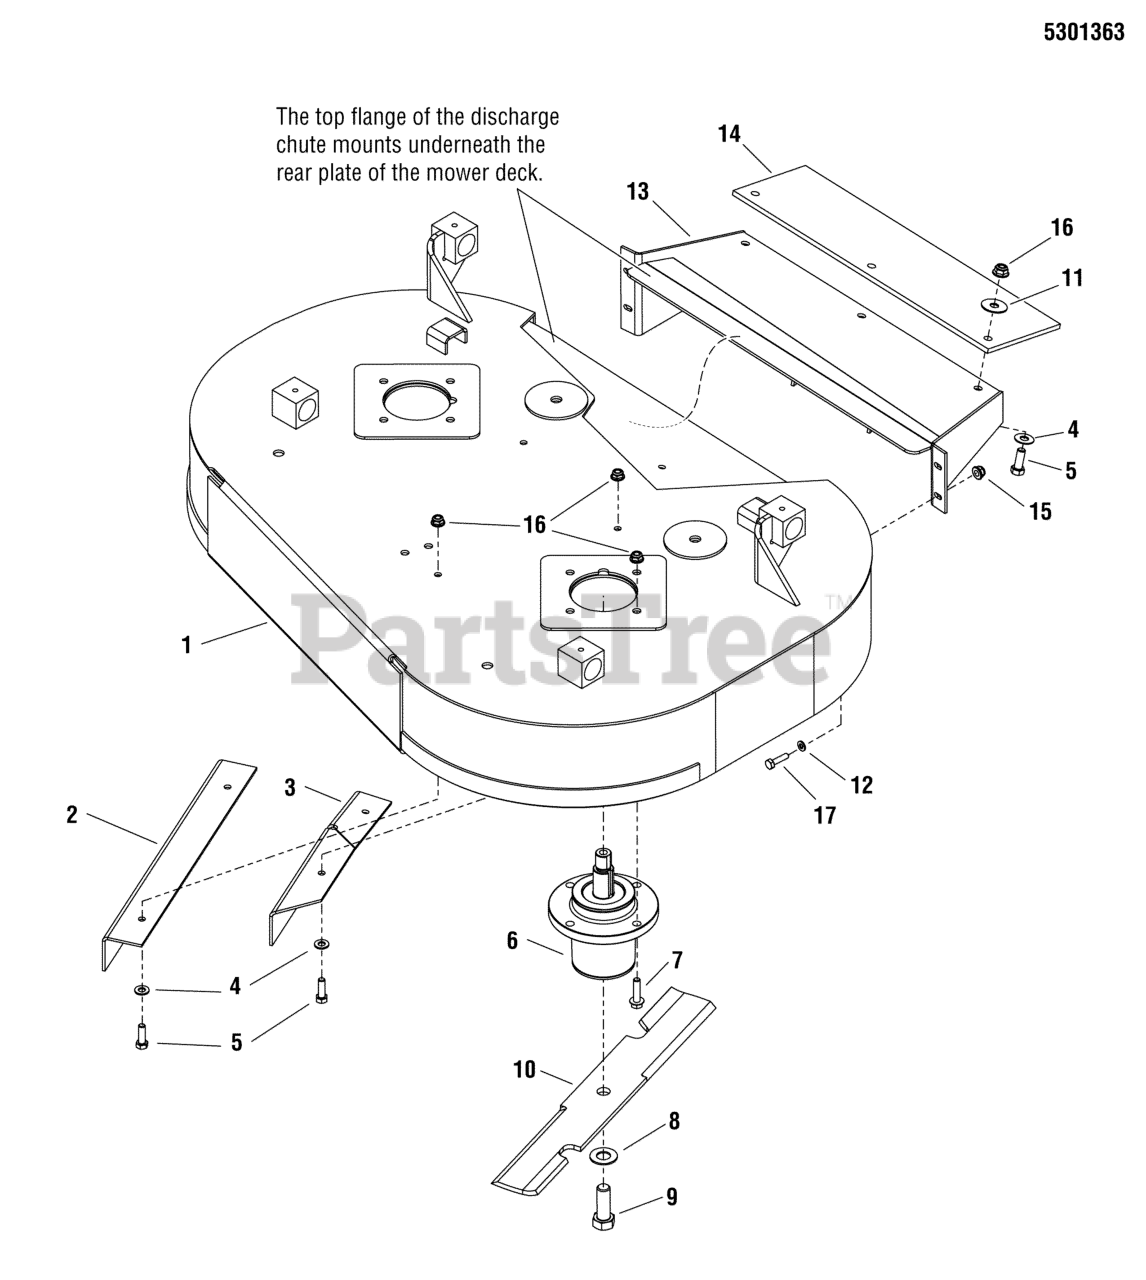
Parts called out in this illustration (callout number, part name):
1	DECK SHELL W/ DECALS, 36" RD SW20CE
2	BAFFLE, 36RD, SNP PRO - RED
3	BAFFLE, ANGLED, 36RD, SNP PRO - RED
4	WASHER, 5/16" SAE
5	BOLT, 5/16-18 X 1 GD5 YZ
6	ASSM, SPINDLE, LOW PROFILE
7	BOLT, 5/16-18 X 1 1/4 FLANGE
8	WASHER, 5/8 GRADE 8, YZ
9	BOLT, 5/8-11 X 1-3/4 GD8
10	BLADE, 18
11	WASHER-3/8 FENDER
12	WASHER, 1/4 SAE
13	WELD, DISCHARGE CHUTE, 36 WB RD
14	FLAP, RUBBER, 36RD
15	NUT, 1/4-20 HEX NYLOCK FLANGE
16	NUT, 5/16-18 HEX NYLOCK FLANGE
17	BOLT, 1/4-20 X 1" GD5 CZ
